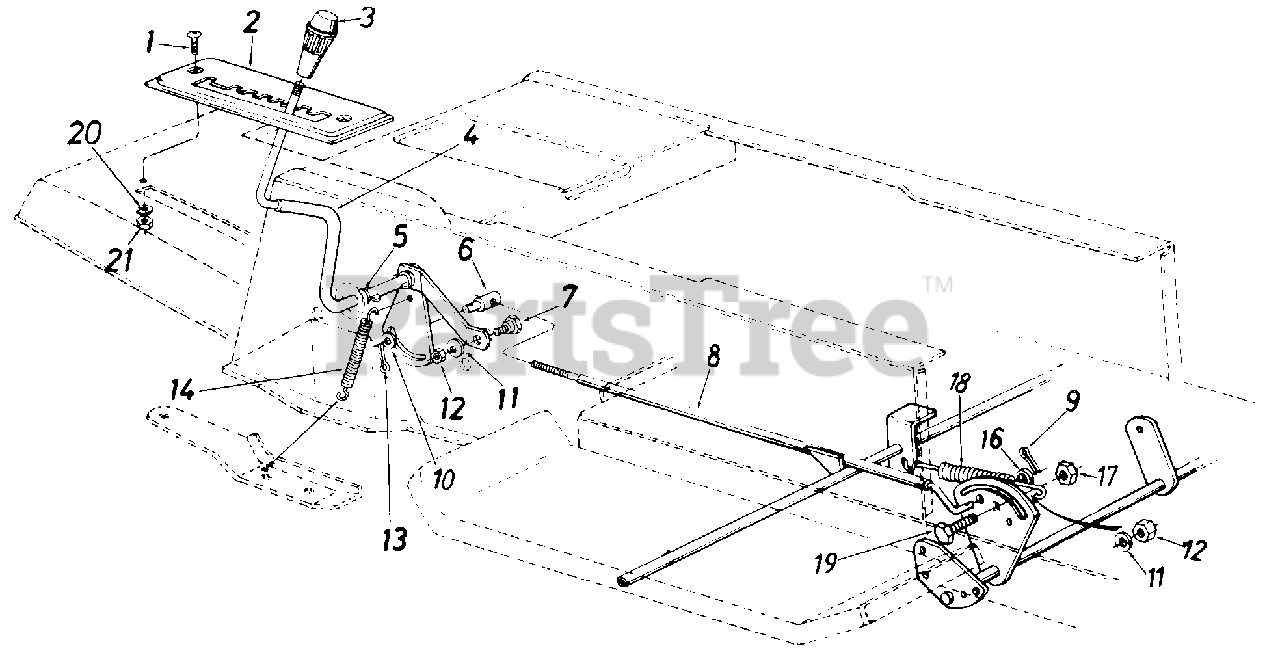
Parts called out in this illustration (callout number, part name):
1	Truss Mach. Scr. 1/4-20 x .75" Lg.
4	Speed Selector Cam Ass'y.
5	Flat Washer .53" I.D. x .93"
6	Ferrule 3/8-24 x .37" Dia.
7	Shoulder Bolt .435" Dia. x .160
8	Speed Control Rod Ass'y.
9	Cotter Pin 3/32" Dia. x .75"
10	Fl-Wash. .385" I.D. x .62" O.D.
11	L-Wash. 5/16" I.D.
12	Hex Nut 5/16-18 Thd.
13	Cotter Pin 3/32 Dia. x .75"
14	Spring
16	Fl-Wash. .47" I.D. x .88" O.D.
17	Hex L-Nut 5/16-18 Thd.
18	Ext. Spring 4.75" Lg.
19	Hex Bolt 5/16-18 x 1" Lg. (Grade 5)
20	L-Wash. 1/4" I.D.
21	Hex Nut 1/4-20 Thd.
